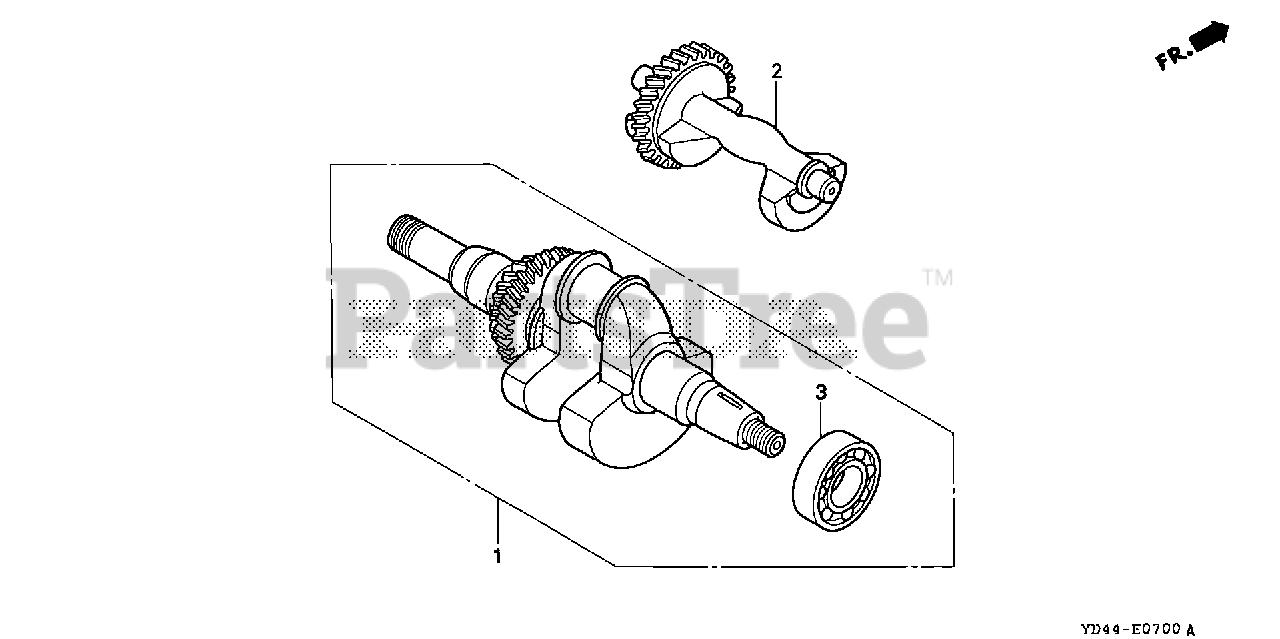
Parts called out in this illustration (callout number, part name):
1	CRANKSHAFT
2	WEIGHT, BALANCER
3	BEARING, RADIAL BALL (6207)
